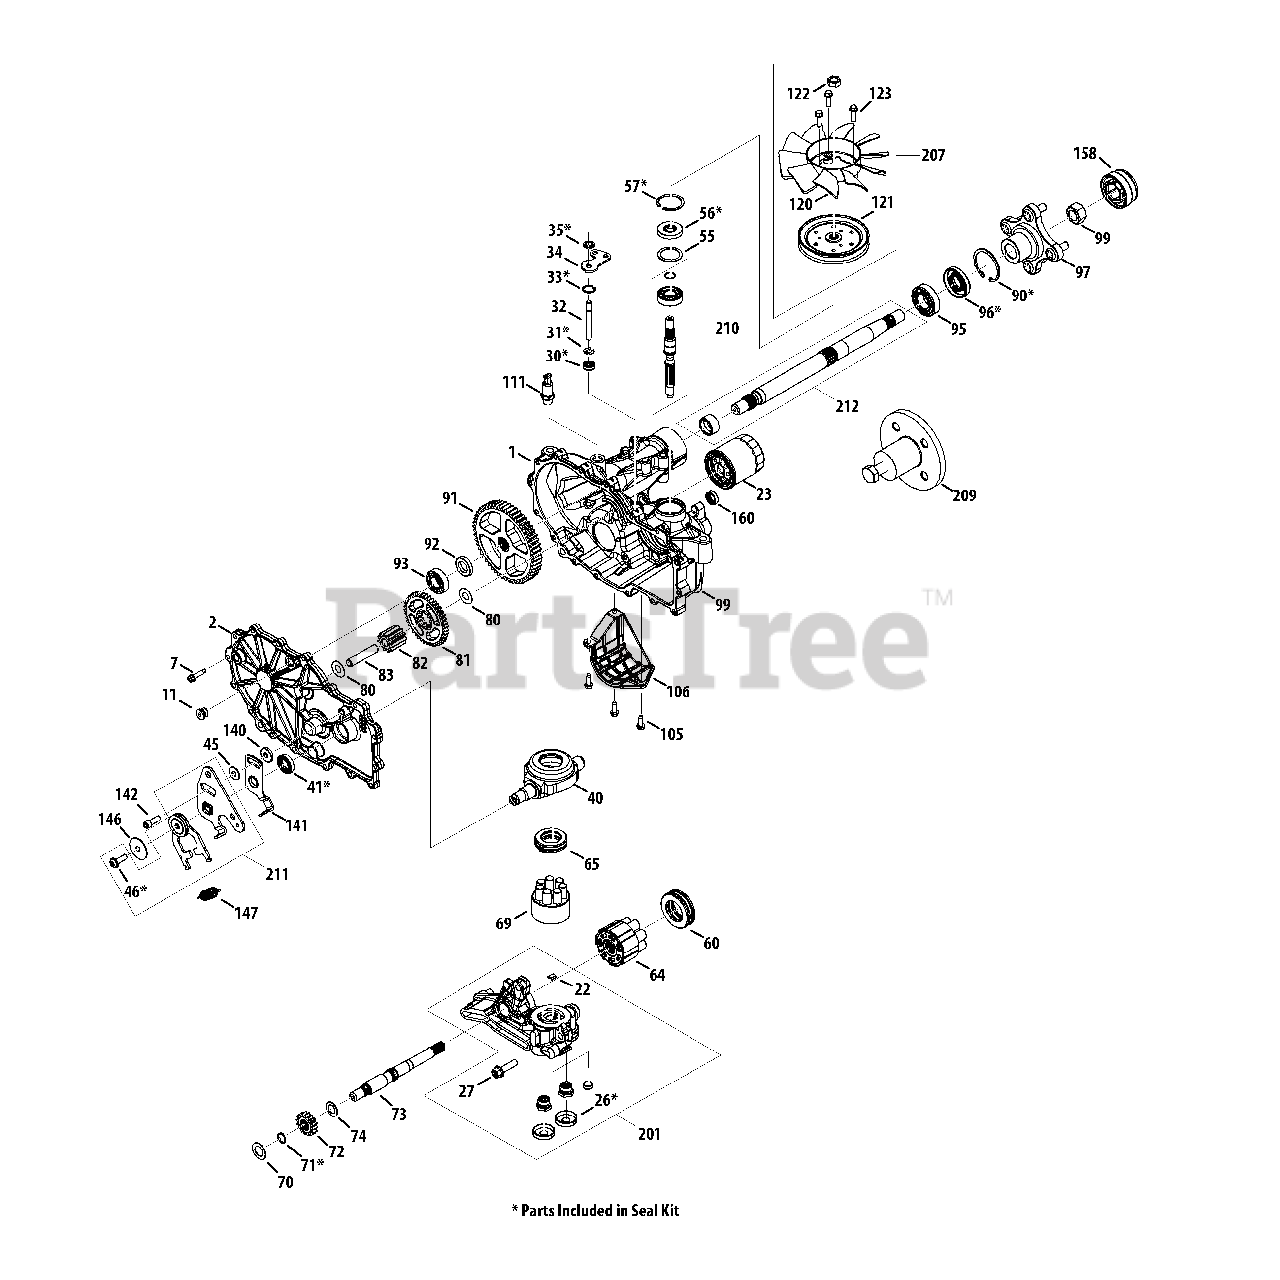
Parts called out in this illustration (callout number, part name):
1	Kit, Housing, Main, LH
2	Kit, Cover, Side, LH
7	Hex Cap Screw, 1/4-20 x 1.125
22	Plate, Bypass
23	Oil Filter
26	Seal, Plug, 1.25 x .25
27	Hex Cap Screw, 3/8-16 x 1.5
30	Seal, Lip .375 x .75 x .25
31	Ring, Ret .375 External
32	Rod, Bypass
33	Ring, Ret .75 Internal
34	Arm, Bypass
35	Ring, Retaining .375 External
40	Trunnion, Swashplate
41	Seal, Lip 12 x 32 x 7
45	Washer, .34 x .88 x .06
46	Hex Cap Screw, 5/16-24 x 1.00
55	Washer, 1.23 x 1.56 x .04
56	Seal, Lip 17 x 40 x 7
57	Ring, Retaining
60	Bearing, Thrust
64	Cylinder Block Assembly
65	Thrust Ball Bearing, 30 x 52 x 13
69	Block 7 Piston Assembly
70	Washer, .63 x 1.0 x .05
71	Retaining Ring, .625
72	Gear, 16t
73	Motor Shaft
74	Washer, .72 x 1.16 x .04
80	Washer, .5 x 1.0 x .03
81	Gear, 43t
82	Gear, 11t
83	Jack Shaft
90	Retaining Ring, 2.06 Internal
91	Gear, 54t
92	Spacer, .75 x 1.32 x .257
93	Ball Bearing, .75 x 40 x 12
95	Ball Bearing, 1.0 x 52 x 15
96	Seal, Lip 25 x 52 x 10
97	Kit, Hub, 4 Bolt
99	Nut, 3/4-16, Hex Lock
105	Hex Cap Screw, 1/4-20 x .75
106	Guard, Filter, LH
111	Fitting, 9/16-18 SAE .5 Barb
120	Fan 7", 10 Blade
121	Disc, Pulley
122	Nut, 1/2-20, Hex Jam
123	Hex Cap Screw, 1/4-20 x .875
140	Spacer, .320 x 1.005 x .179
141	Neutral Right Arm
142	Hex Cap Screw, 5/16-24
146	Washer, .343 x 1.5 x .062
147	Extension Spring, .57 x 2"
160	Seal, Lip, .625 x .875 x .25
201	Kit, Center Section, LH
207	Kit, Fan & Pulley
209	Hub Puller, 4 Bolt
210	Kit, Input Shaft
211	Kit, RTN, Bidirectional
212	Kit, Shaft, Axle
